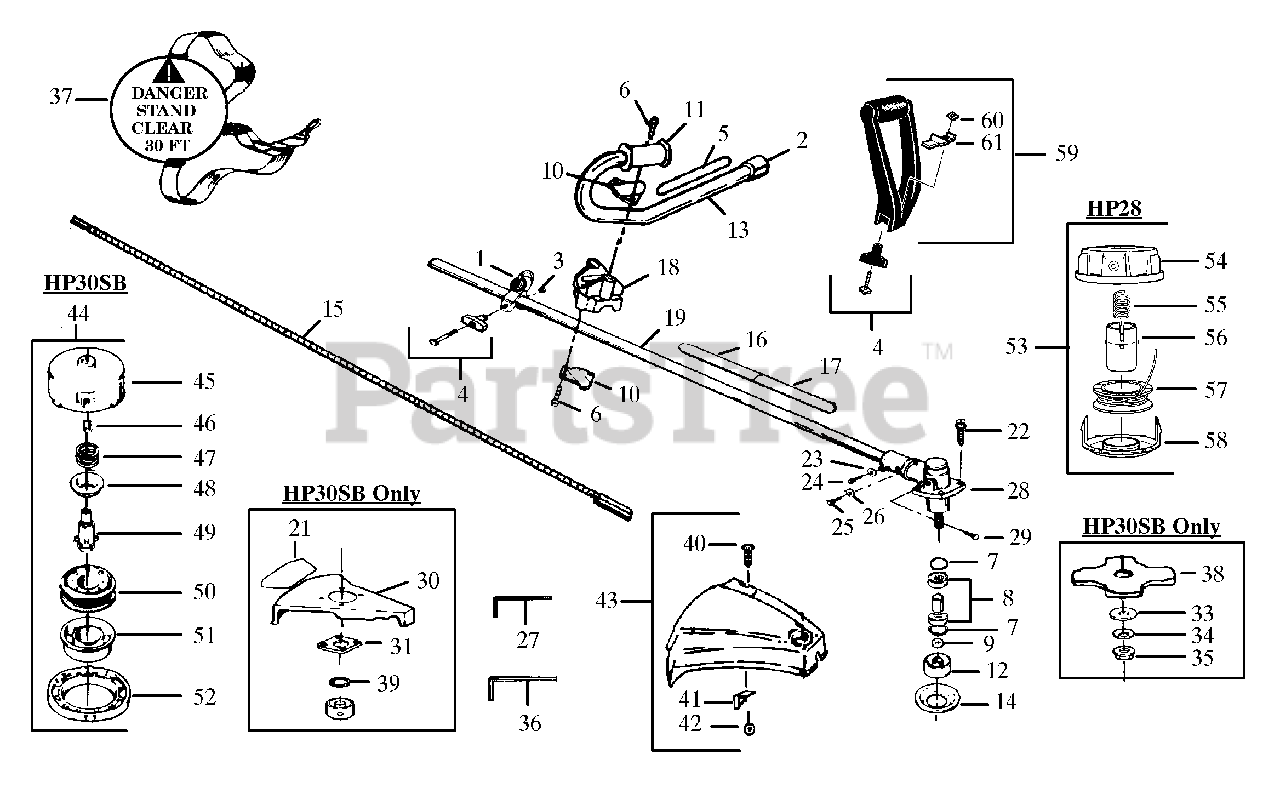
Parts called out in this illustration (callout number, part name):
1	Clamp Harness Ass'y.
2	Handlebar Cap
4	"T" Handle Ass'y.
5	Handlebar Warning Decal
7	Retainer
8	Bearing & Spacer Kit
10	Handlebar Bracket
11	Handlebar Grip
12	Dust Cup
13	Handlebar
14	Grass Washer
15	Drive Shaft Model HP28
15	Drive Shaft Model HP30SB
16	Shaft Warning Decal-Upper
17	Shaft Warning Decal-Lower
18	Handlebar Clamp
19	Drive Shaft Housing Model HP28
19	Drive Shaft Housing Model HP30SB
21	Blade Direction Decal
22	Screw
23	Lockwasher
26	Lockwasher
27	Hex Wrench (5/32)
28	Gear Box Ass'y.
30	Shield
31	Shield Retention Plate
34	Washer
36	Hex Wrench (3/16)
37	Shoulder Strap
38	Weed Blade
41	Line Limiter
43	Shield Kit Ass'y.
44	Cutting Head Ass'y.
45	Hub
46	Line Saver
48	Spring Adaptor
49	Drive Gear
50	Spool w/ Line
51	Release Button
53	Cutting Head Ass'y.
54	Hub Ass'y.
56	Release Button
57	Spool w/Line
59	Assist Handle Kit
